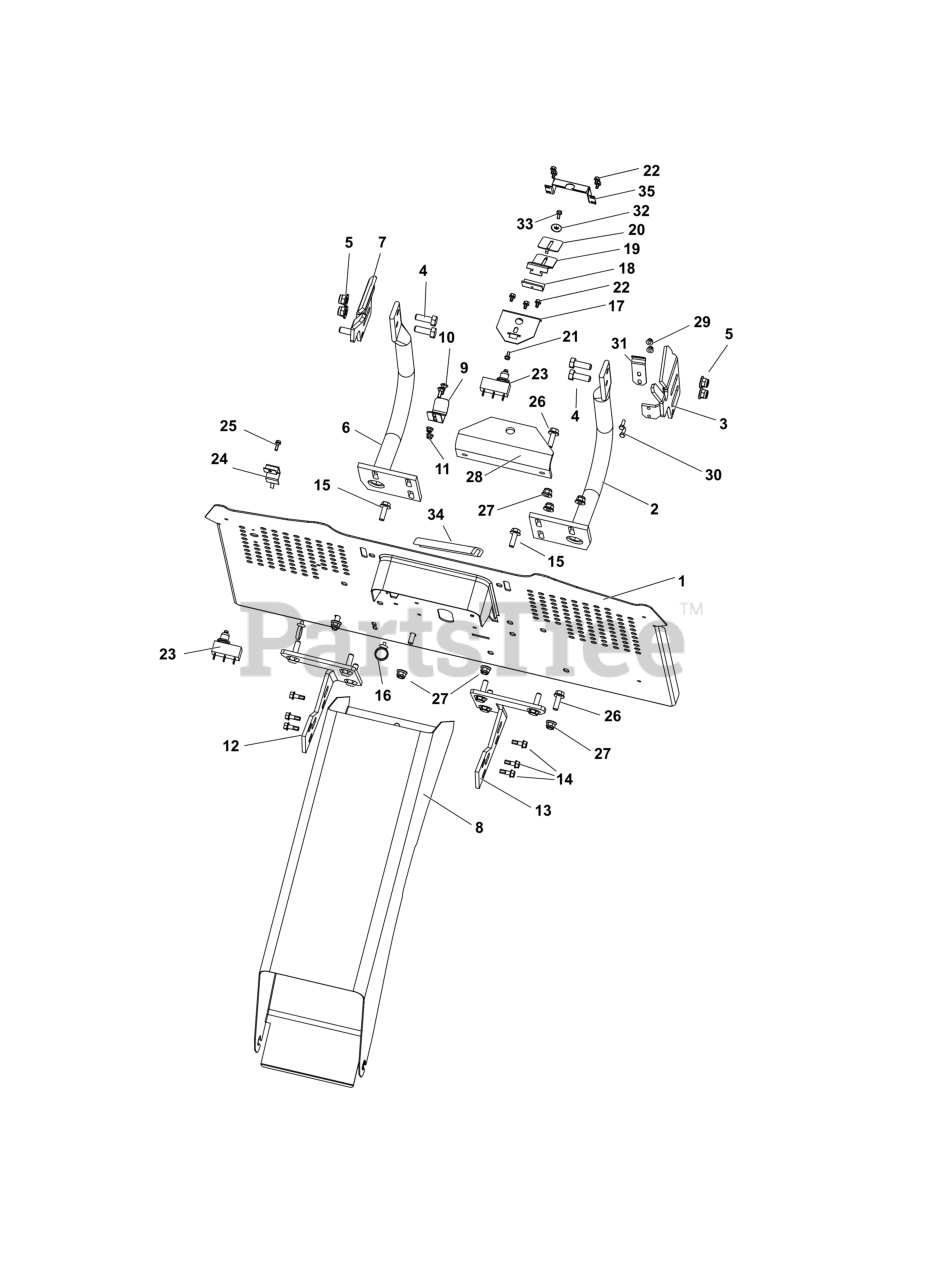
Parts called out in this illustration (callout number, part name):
1	PLATE, Back
8	CHUTE, Discharge
23	MICROSWITCH
24	SWITCH, Cover
